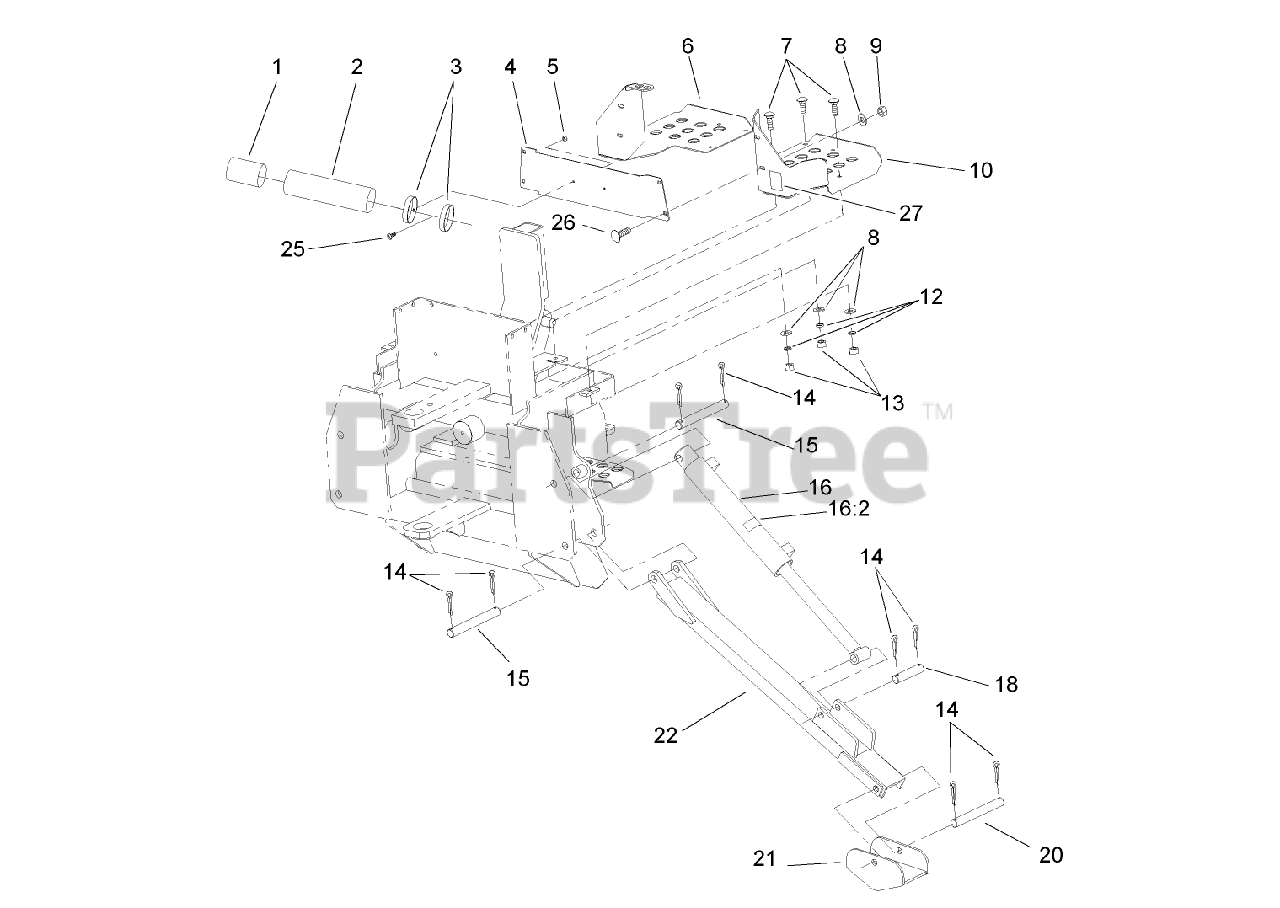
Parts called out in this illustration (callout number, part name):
1	CAP-HOUSING
2	TUBE-MANUAL
3	CLAMP-R
4	PLATE-COVER, VALVE
5	NUT-LOCK, NI
6	PLATE-FLOOR, RH
7	BOLT-CARR
8	WASHER-PLAIN
9	NUT-LOCK, NI
10	PLATE-FLOOR, LH
12	WASHER-LOCK
13	NUT-HEX
14	PIN-COTTER
15	PIN-PIVOT
16	HYDRAULIC CYLINDER ASM
18	PIN-PIVOT
20	PIN ASM
21	STABILIZER PAD ASM
22	STABILIZER LEG ASM
26	BOLT-CARR
27	DECAL-I/O, VALVE
